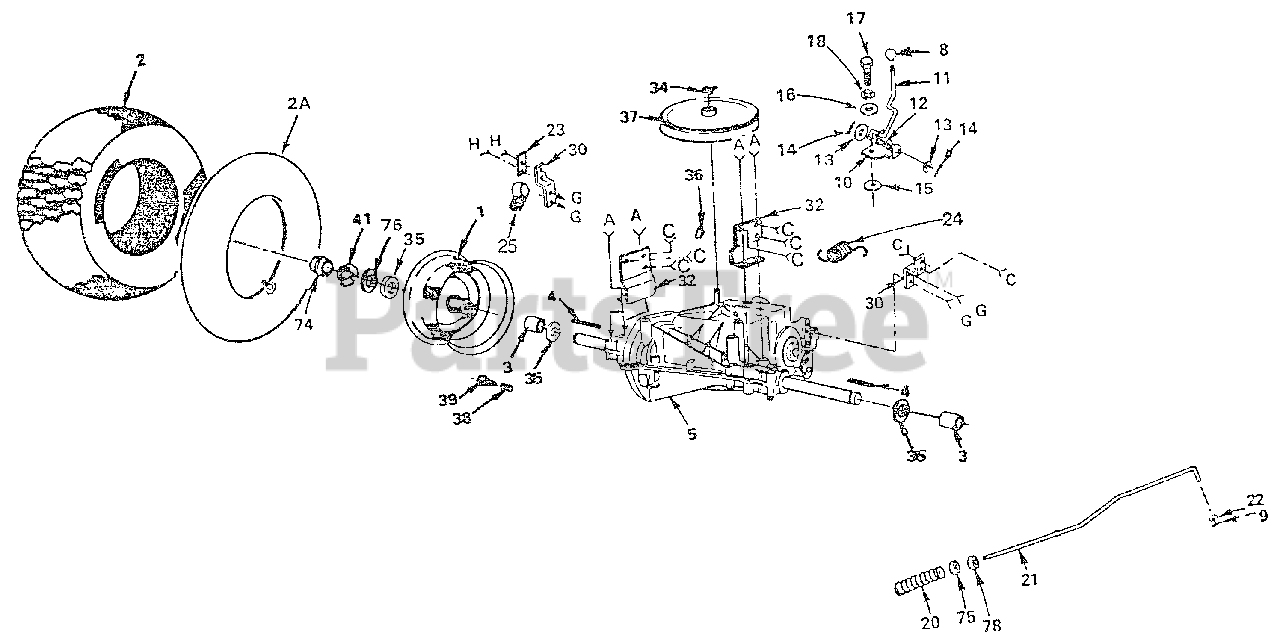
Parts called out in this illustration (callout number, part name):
1	Rim Assembly 8" Rear
2	Tire 18 x 9.50 - 8 (Tubeless)
2A	Tube - Tire
3	Spacer-Split
4	Key - Square 3/16 x 2
5	Transaxle - 6 Speed, Mode No.4150-61
8	Knob - Control
9	Cotter Pin -1/8 x 3/4
10	Plate - Rod, Shift
11	Rod - Shifter
12	Spring - Torsion
13	Washer 15/32 x 3/4 x 16 Ga.
14	Pin, Cotter 1/8 x 1
15	Washer- Shift Plate
16	Washer 9/32 x 3/4 x 10 Ga.
17	Bolt - Hex 1/4- 28 x 3/4, Gr.8
18	Washer-Lock 1/4
20	Spring- Rod, Brake
21	Rod - Brake
22	Washer 13/32 x 13/16 x 16 Ga
23	Plate - Strap, Torque
24	Spring - Brake Return
25	Clip
30	Strap - Torque
32	Bracket - Transaxle
34	Ring - Klip
35	Washer- 25/32 x 1-1/4 x 16 Ga.
36	Woodruff Key - 3/16 x 34
37	Pulley -Transaxle
38	Cap - Valve
39	Stem - Valve
74	Cap - Hub, Rear
75	Nut- Centerlock 3/8-16
76	Washer 25/32 x 1-5/8 x 16 Ga.
78	Nut - Hex Jam, 3/8 -16
